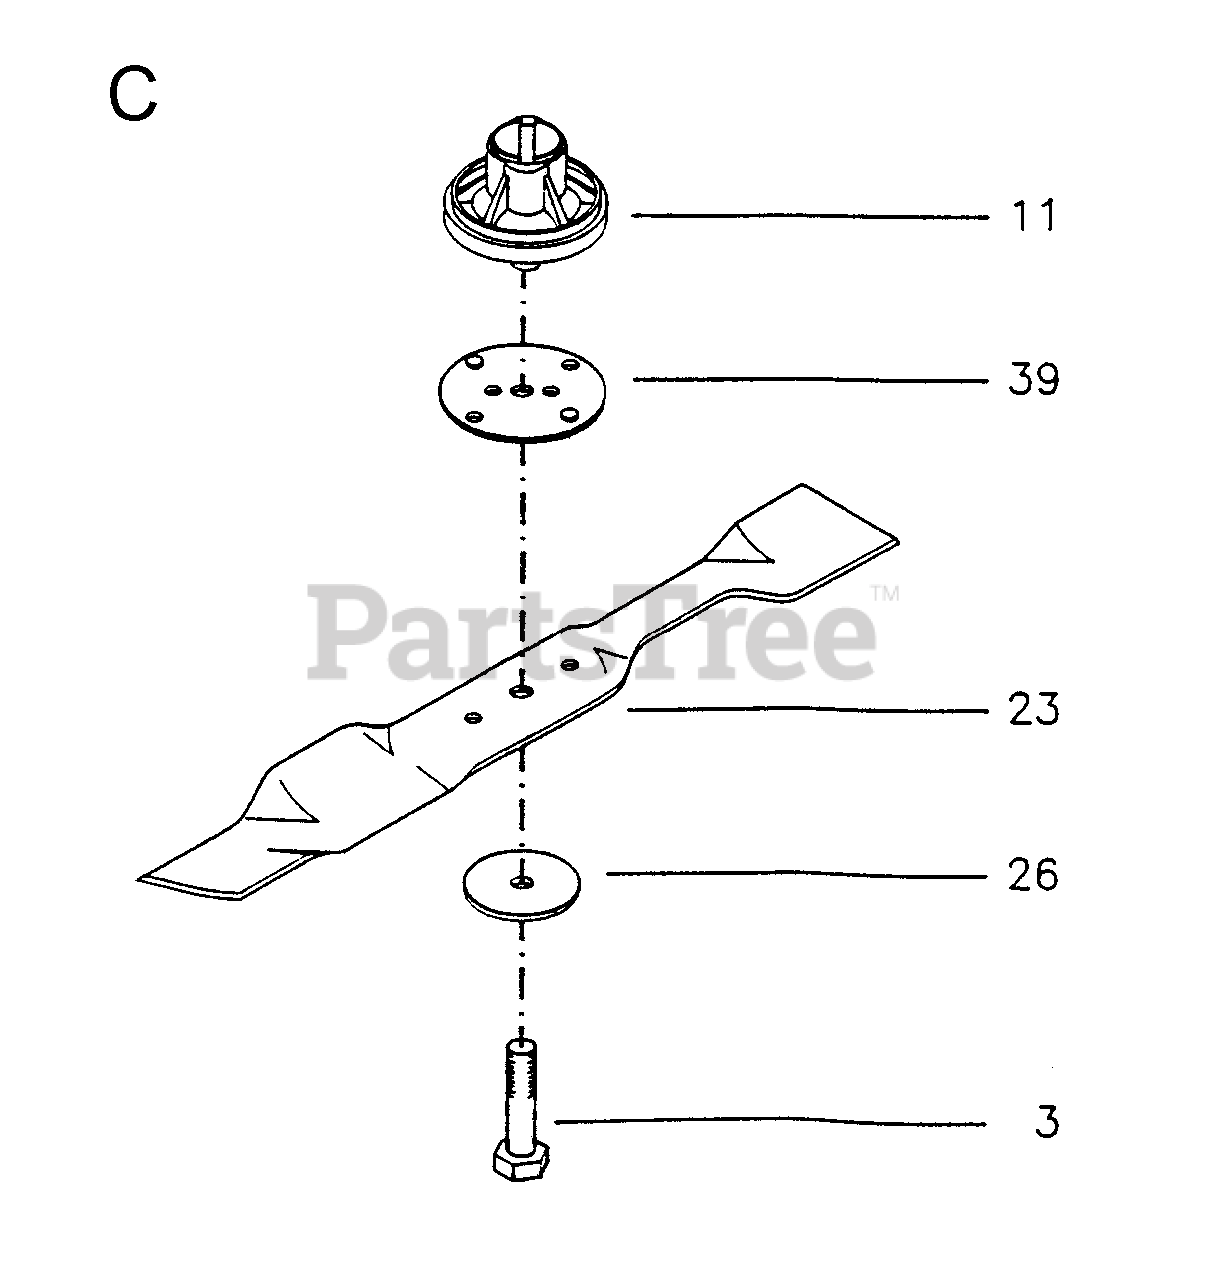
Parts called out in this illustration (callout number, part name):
3	REPL BY 515 12 39-31
11	BLADE ADAPTER
39	STEEL PLATE ADAPTER
